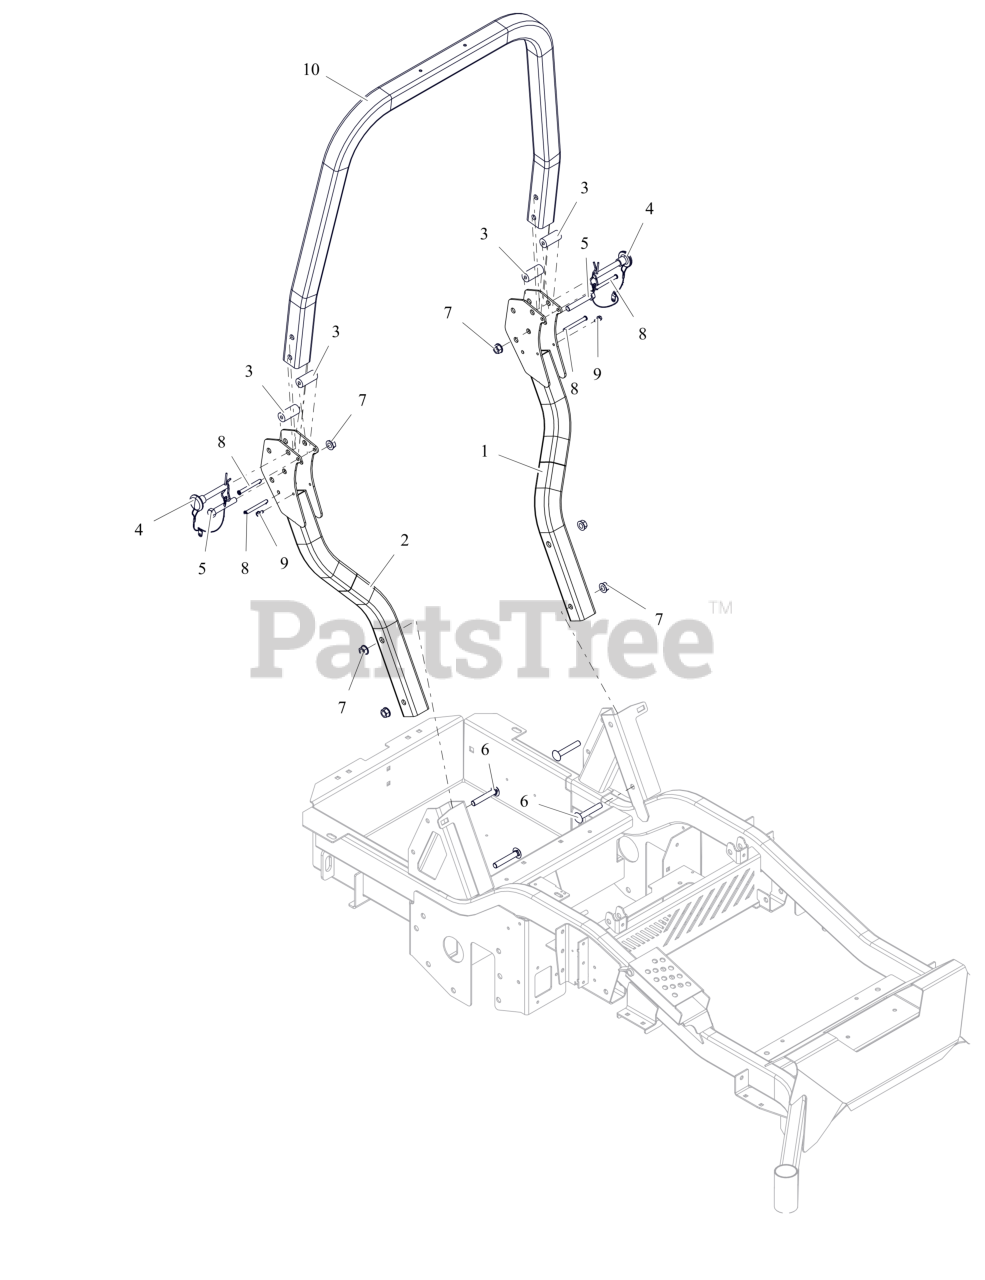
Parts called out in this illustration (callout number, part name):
1	WLDMT, LH ROPS LOWER
2	WLDMT, RH ROPS LOWER
3	BUMPER, ROPS ANTI-VIBRATION
4	PIN, ROPS W/LANYARD
5	BLT, HEX .50-13X3.00 G5 ZCC
6	BTL,RHSSN .500-13 X 3 G5 ZCC
7	NUT-LK-CTR-FLG .500-13 GG ZCC
8	PIN, SLIC .312 X 2.57
9	SCR-TAP .25-20X.50 HWH ZCC
10	TUBE, ROPS UPPER HOOP
